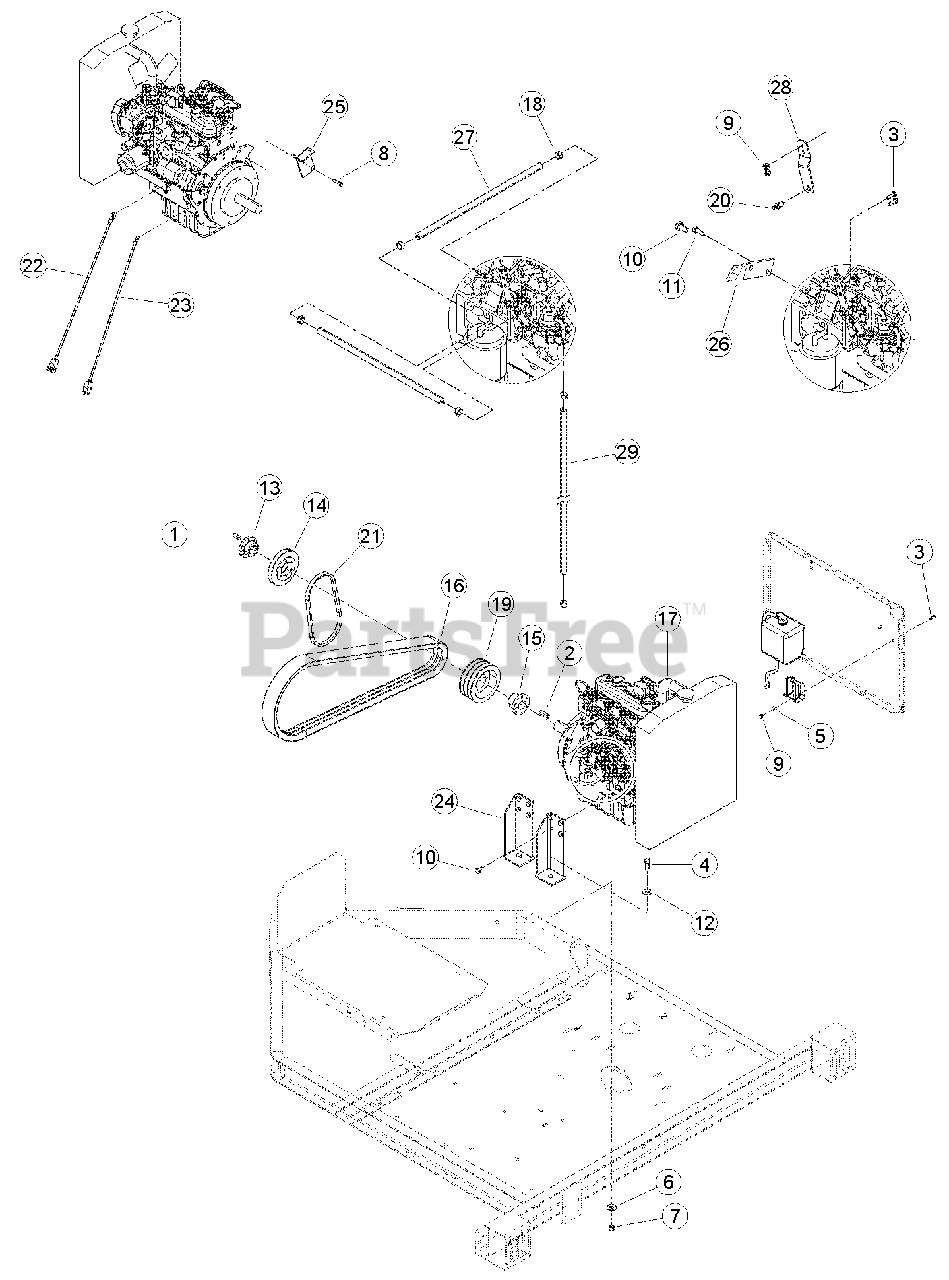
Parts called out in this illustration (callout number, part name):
1	KEY, 3/8 SQUARE X 1-1/4 LONG
2	KEY, 3/8 SQUARE X 1-3/4 LONG
3	BOLT, 1/4 X 3/4 HEX HD GR5 ZP
4	BOLT, 1/2 X 1-1/4 HEX HD GR5 ZP
5	WASHER, 1/4 FLAT ZP
6	WASHER, 1/2 FLAT ZP
7	NUT, 1/2 CENTERLOCK GRB ZP
8	BOLT, 5/16 X 1 CRG GR5 ZP
9	NUT, 1/4 NE NYLOCK ZP
11	BOLT, M 8-1.25 X 20 HHD GR8.8 ZP
12	WASHER, 1/2 HI-STRENGTH SAE ZP
13	BUSHING, SDS 1-7/16
14	SHEAVE, 1B5.2 SDS
15	BUSHING, SD 1-7/16
16	BELT, 3B83 BANDED
17	ENGINE, KUBOTA DIESEL
18	CLAMP, 9/16 SPRING
19	SHEAVE, 3BQ5.6 SD
20	CABLE STOP, BOWDEN PIN #6170
21	BELT, BX30
22	CABLE, 72 IN. POSITIVE BATTERY
23	CABLE, 72 IN. NEGATIVE BATTERY
24	WELDMENT, ENGINE MOUNT
25	ANGLE, SPRING ANCHOR
26	STRIP, CABLE ANCHOR
27	HOSE, 15 IN. FUEL LINE
28	STRIP, THROTTLE CONTROL
29	HOSE, 38 IN. FUEL LINE
